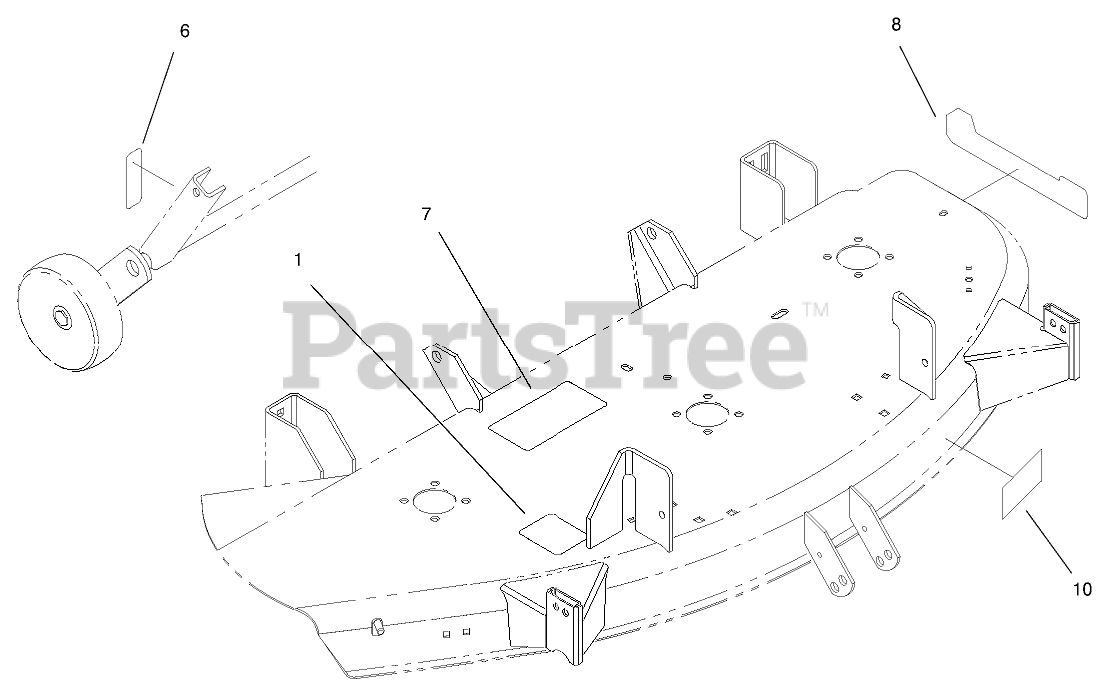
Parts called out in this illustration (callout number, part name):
1	DECAL-BELT ROUTING
6	DECAL-HOC
7	DECAL-BELT ROUTING
8	Decal-Recycler (only on: 78364)
10	DECAL-ADJUSTMENT, WHEEL
